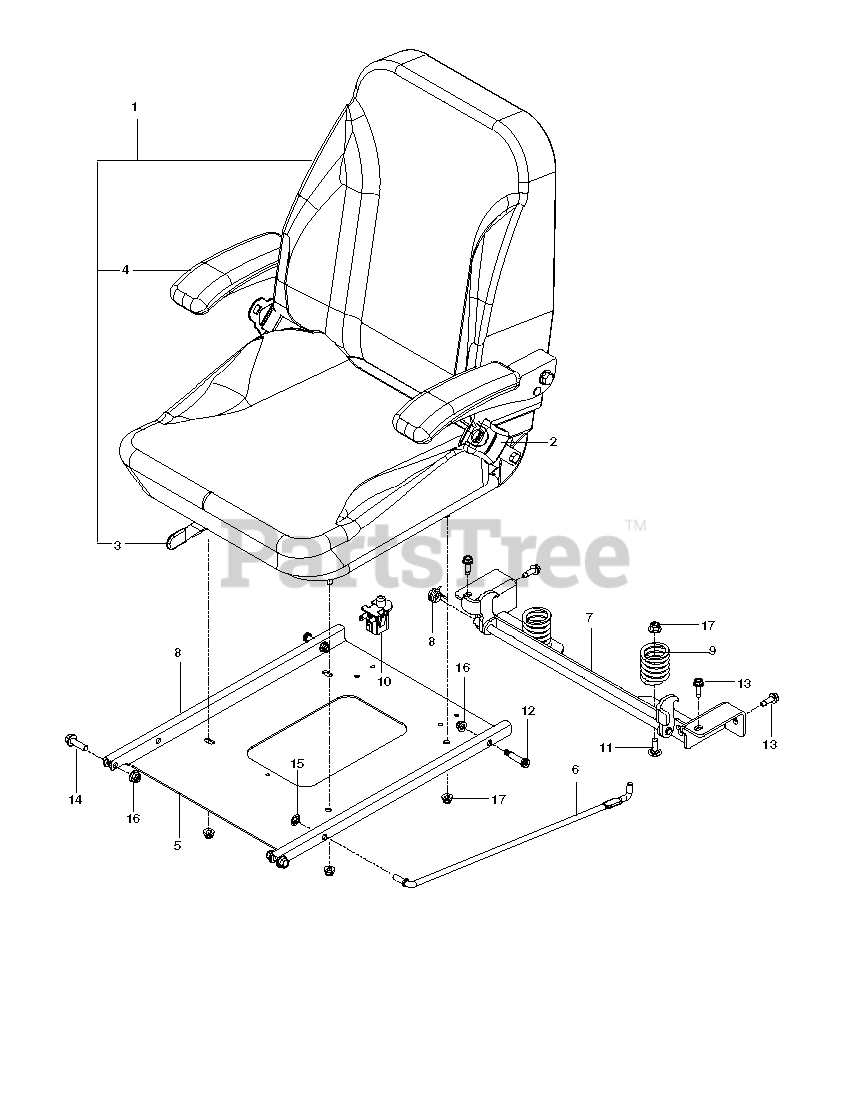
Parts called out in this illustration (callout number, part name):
1	SEAT ASSY
3	TRACK KIT
4	ARMREST, LT
5	PAN, SEAT, BLACK
6	ROD, SEAT
7	LATCH, SEAT, BLK
8	SPRING, TORSION
9	SPRING, SEAT
10	SEAT SWITCH
11	RHSNB 3/8C X 1
12	BOLT, SHOULDER 3/8 X 1.25
16	NUT 3/8-16 HEX FLG NYLOC ZD
17	5/16-18 NYLOC FLANGE NUT
